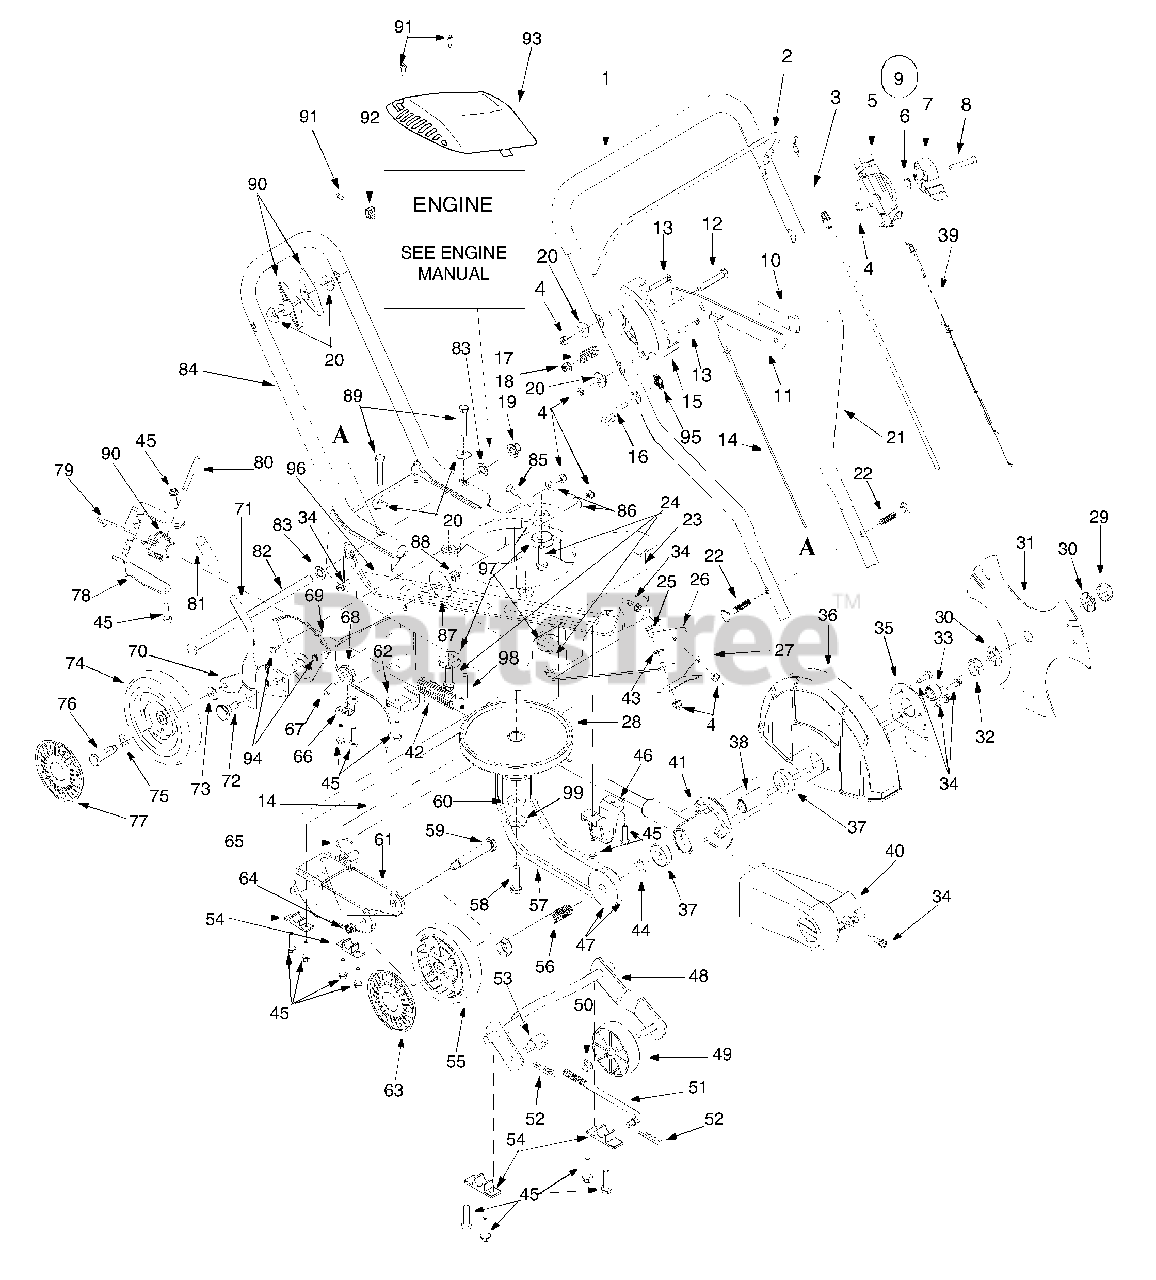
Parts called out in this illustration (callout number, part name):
1	Foam Grip
3	Control Cable
4	Hex Lock Nut 1/4-20 Thd.
5	Throttle Hsg.
6	Curved Washer .663 x .980 x .014
7	Throttle Lever
8	Screw Oval C-Sunk 1/4-20 x 1.81 Lg.
9	Throttle Comp.
10	Depth Lever Grip
12	Hex Screw 5/16-18 x 2.0 Lg.
13	Carriage Bolt 1/4-20 x 1.50 Lg.
14	Depth Cable
15	Depth Bracket
16	Eye Bolt 1/4-20
17	Compression Spring .550 O.D. x 1.3
18	Hex Lock Nut 5/16-18
19	Push Cap x 1/2 Rod
20	Washer .320 ID x .93 O.D.
23	Edger Base Ass'y
24	Tapp Screw w/Hex Lock Wash 3/8-16
25	Hex Screw 1/4-20 x .50 Lg.
26	Discharge Shield Deflector
27	Deflector Keeper
28	Engine Pulley
29	Hex Jam Nut 5/8-18
30	Bell Washer .63 I.D. x 1.25 O.D. x .18
32	Hex Jam Nut 5/8-18
33	Spacer .628 x .875 x .545 Lg.
34	Hx Scr. w/Wash.: TT: 1/4-20 x .750 Lg.
37	Ball Bearing .62 I.D. x 1.38 O.D. x .4
38	Spacer .628 x .875 x 1.818 Lg.
39	Throttle Cable
40	Belt Guard
41	Spindle w/Insert
42	Compression Spring: Arbor
43	Flat Washer .283 I.D x .75 O.D. x .030
44	Flat Washer .635 I.D. x .93 O.D. x .06
45	Hex Screw w/Wash 1/4
46	Front Rod Handler
47	Pulley
50	Push Cap x 3/8 Rod
51	Rod 5/16-24
52	Cotter Pin .072 x 1.12
53	Ferrule 5/16-24 x .312
54	Black Bushing .515 Dia x .62
55	Wheel 7" x 2" Link w/BB
56	Hex Bolt 5/8-18 x 5.25 Lg.
57	V-Belt
58	Hex Screw: 3/8-24 x 1.50 Lg.
59	Shoulder Screw .500 x 2.62: 3/8-16
60	Bell Wash. .396 I.D. x 1.140 O.D. x .095
61	Front Wheel Brkt Ass'y.
62	Rear Rod Handler
63	Hubcap: Spoke w/Hole Yellow
64	Jam Lock Nut 3/8-16
65	Torsion Spring
68	Cable Roller Pulley
69	Index Plate
70	Pivot Arm
71	Spring Lever
72	Shoulder Bolt .500 x .434 Lg.
73	Bell Wash. .401 I.D. x .870 O.D. x .063
74	Wheel - 8" x 2" Link Yellow w/BB
75	Wave Washer .510 I.D. x .750 O.D.
76	Shoulder Bolt .498 x 1.445: 3/8-16
77	Hubcap: Radial Spoke Yellow
78	Tilt Bracket
79	Adj. Lever Ass'y
80	Pin 1/4 x 2.0" Lg.
81	Foam Grip
82	Curb Axle
83	Flat Wash. .531 I.D. x .875 O.D. x .06
86	Flat Wash. .285 I.D. x 1.25 O.D. x .06
87	Flat Wash. .406 I.D. x 1.92 O.D. x .06
88	Hex Lock Nut 3/8-16
89	Hex Screw 5/16-18 x 1.75 Lg.
90	Torsion Spring
90	Wing Knob Nut 5/16-18
91	Hex Scr. w/Wash.:T: #10-32 x .625 Lg.
92	Clamp B&S Throttle
93	Engine Shroud
94	Screw Std. 1/4-20 x .75 Lg.
95	Handle Knob
98	Roll Pin
99	Flat Washer .38 ID x 1.38 OD x 1.25
